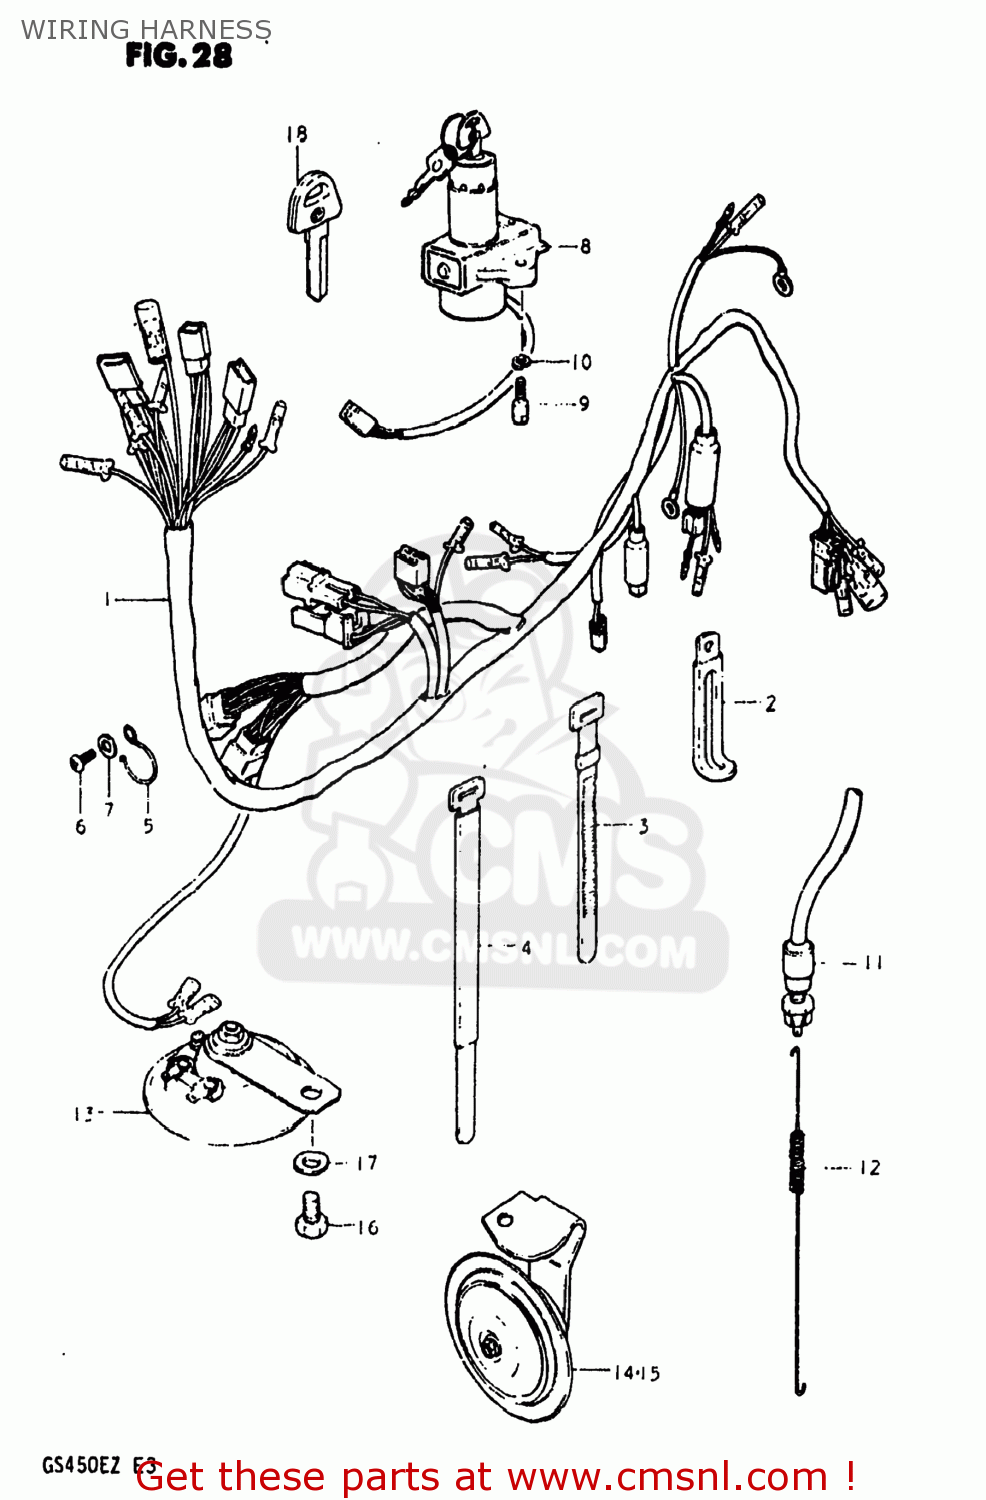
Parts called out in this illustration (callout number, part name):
1	HARNESS,WIRING
2	CLAMP
3	CLAMP(L:80)
4	CLAMP
5	GUIDE,WIRING HARNESS
6	SCREW 6X12
7	WASHER
8	LOCK ASSEMBLY,STEERING
9	BOLT
10	LOCK WASHER
11	SWITCH ASSEMBLY,STOP LAMP
12	SPRING
13	HORN ASSEMBLY,LOW PITCH
14	HORN ASSEMBLY
15	HORN ASSEMBLY
16	BOLT 8X12
17	WASHER
18	KEY,BLANK
